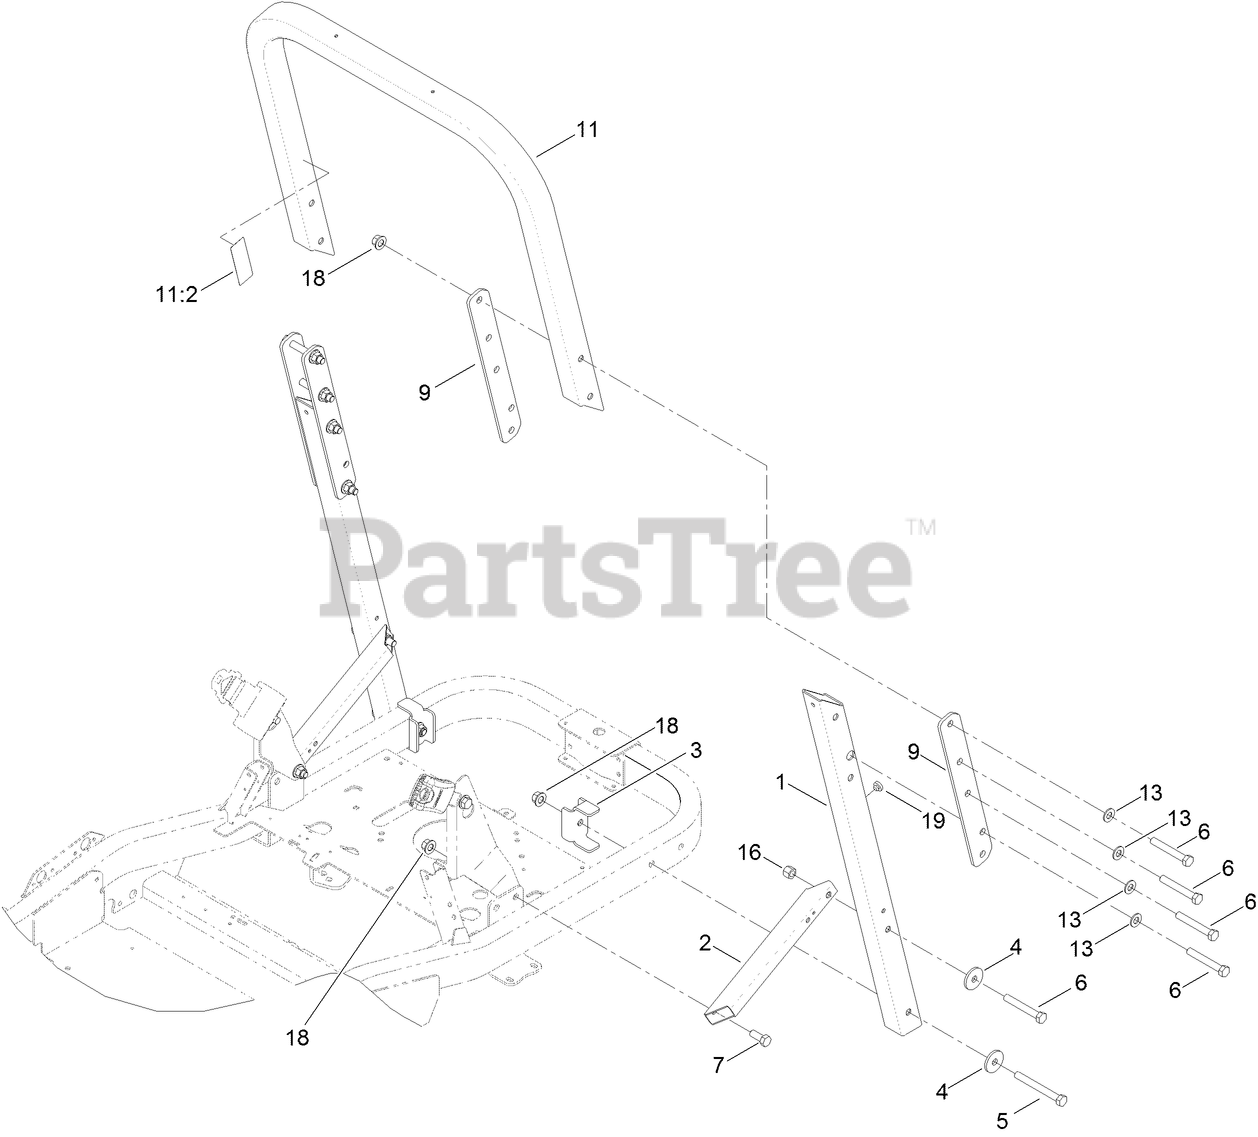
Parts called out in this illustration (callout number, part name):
1	TUBE-ROPS, LOWER
2	TUBE-SUPPORT, ROPS
3	BRACKET-REINFORCING
4	WASHER-THRUST
5	SCREW-HH
6	SCREW-HH
7	SCREW-HH
9	PLATE-ROPS
11	UPPER ROPS ASM
11:2	DECAL-ROPS, WARNING
13	WASHER-FLAT
16	NUT-HEX
18	NUT-LOCK
19	BUMPER
